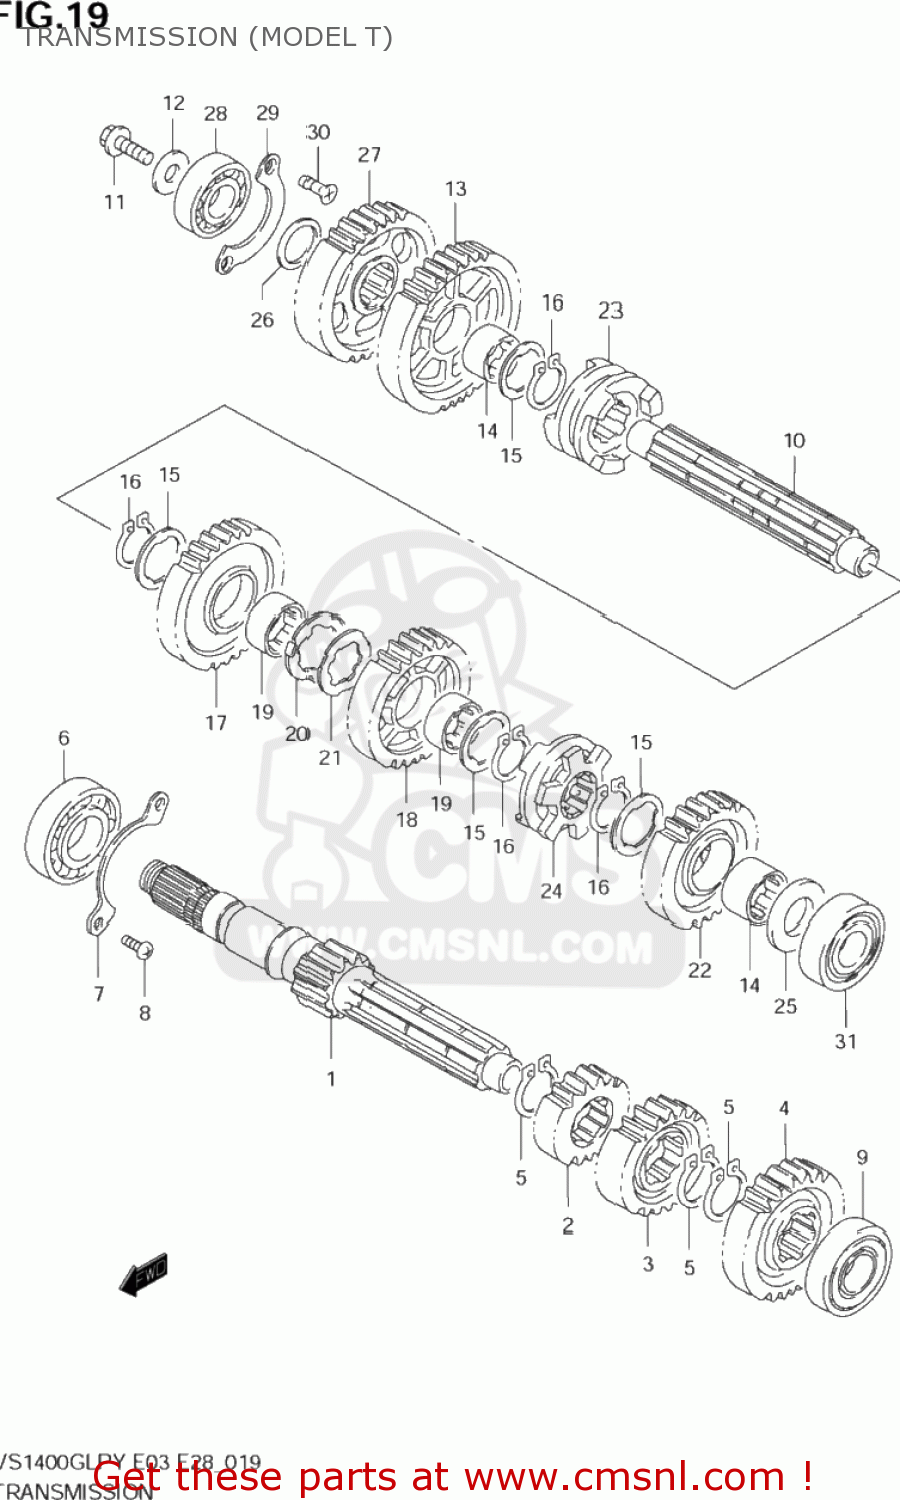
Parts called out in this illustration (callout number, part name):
1	SHAFT,COUNTER
2	GEAR,SECOND DRIVE
3	GEAR,3RD DRIVE
4	GEAR,FOURTH DRIVE
5	CIRCLIP
6	BEARING(25X62X17)
7	RETAINER,CNTR SHAFT BEARING
8	SCREW
9	BEARING(20X52X15)
10	SHAFT,DRIVE
11	BOLT(10X24)
12	WASHER
13	GEAR,FIRST DRIVEN
14	BUSH
15	WASHER,LOCK
16	CIRCLIP
17	GEAR,SECOND DRIVEN
18	GEAR,3RD DRIVEN
19	BUSH,3RD DRIVEN GEAR
20	WASHER
21	WASHER,LOCK
22	GEAR,FOURTH DRIVEN
23	DOG,SLIDING NO.1
24	DOG,SLIDING NO.2
25	WASHER
26	WASHER(22X32X3)
27	GEAR,OVER DRIVING DRIVE(NT:34)
28	BEARING(22X56X16)
29	RETAINER,CNTR SHAFT BEARING
30	SCREW
31	BEARING(20X52X15)
